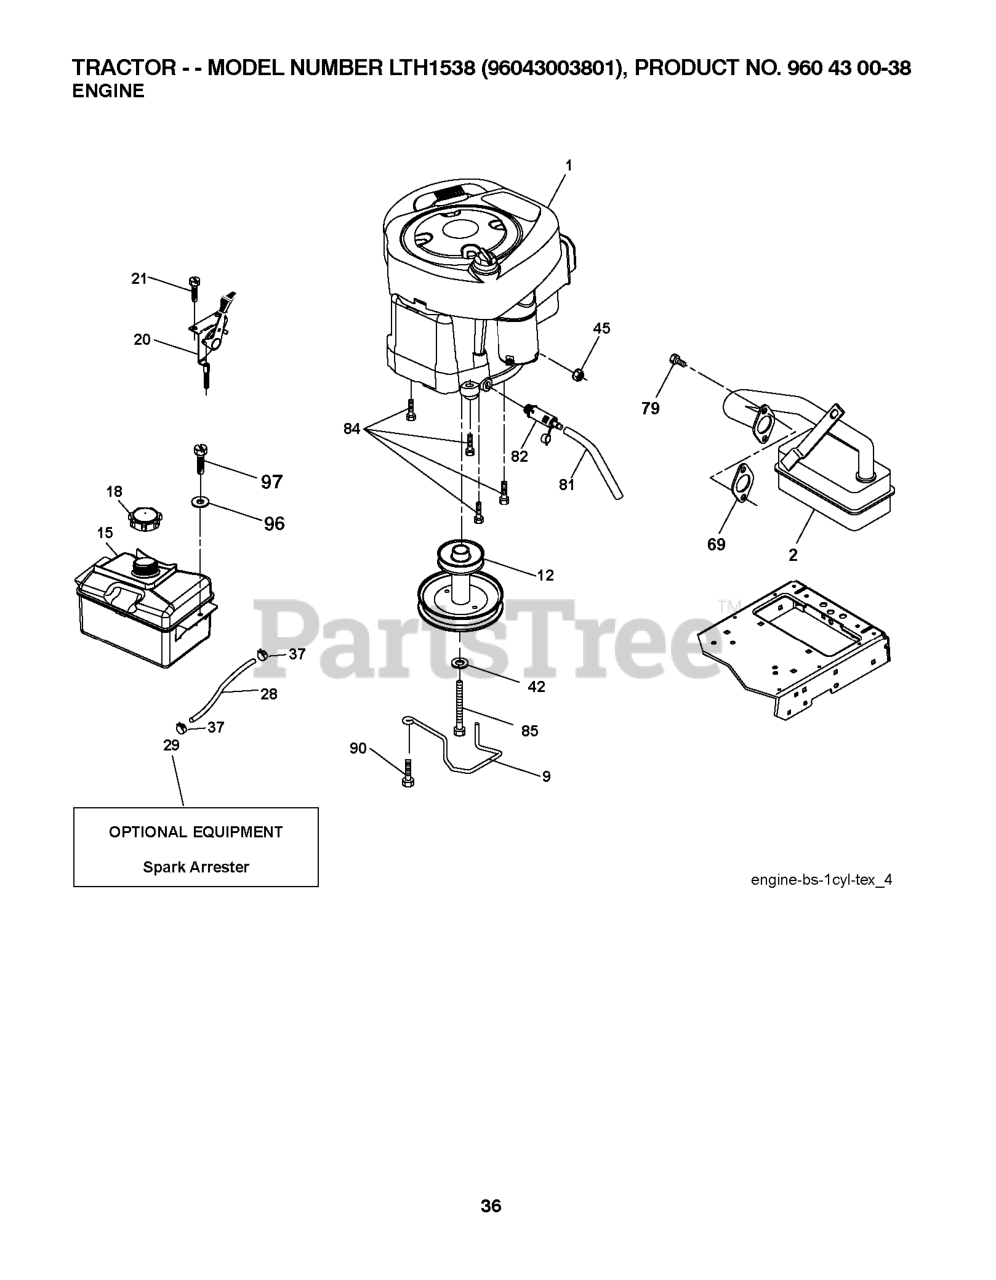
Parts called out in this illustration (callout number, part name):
2	MUFFLER.LT.BRIGGS.14HP.IC/OHV
9	KEEPER.BELT.ENGINE.3.25 (3 2)
12	PULLEY ENGINE
15	RP TANK FUEL FRT 1.5 GAL
18	FUEL CAP
20	CONTROL.TH/CK.C.
21	SCREW
28	LINE.FUEL.20"FRONT.EMI
29	KIT.SPARK ARRESTOR 794945 B&S
37	HOSE CLAMP
42	LOCKWASHER
45	NUT
69	REPL BY 532 27 22-93
79	SCREW.SOCKET HD.5/16-1
81	TUBE, DRAIN OIL ASM.
82	PLUG DRAIN OIL EASY
84	SCREW.3/8-16
85	BOLT HEX 7/16-20X4-1/4"
90	SCREW 3/8-16X1
97	SCREW HEXWSHR 1/4-20X3/4
